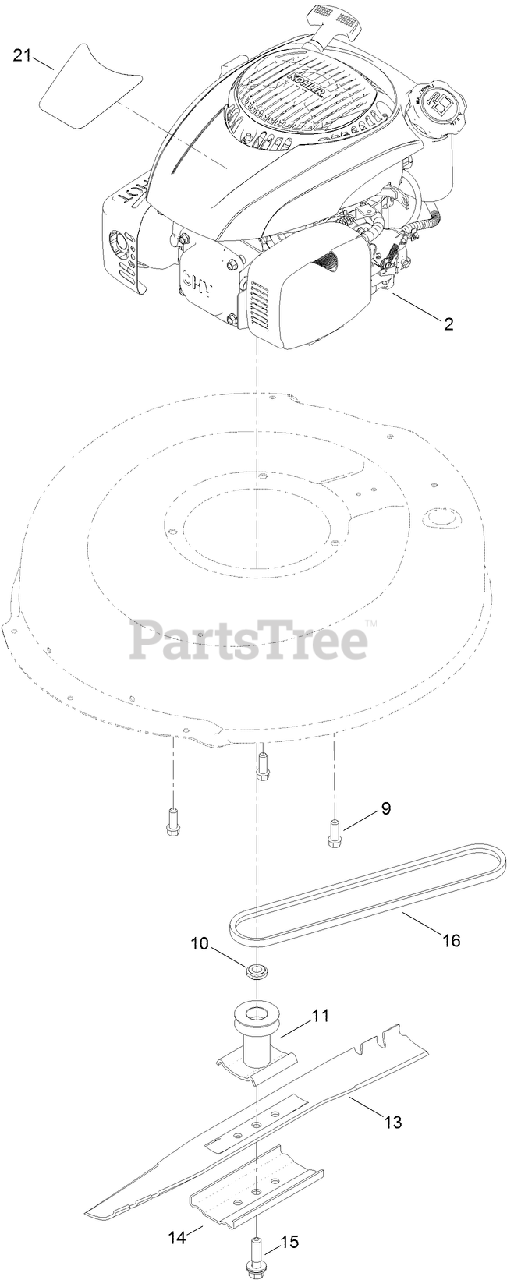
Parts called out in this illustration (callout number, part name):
9	SCREW-TAPTITE
10	SPACER-DRIVER
11	DRIVER-BLADE
14	SUPPORT-BLADE
15	BOLT-BLADE
